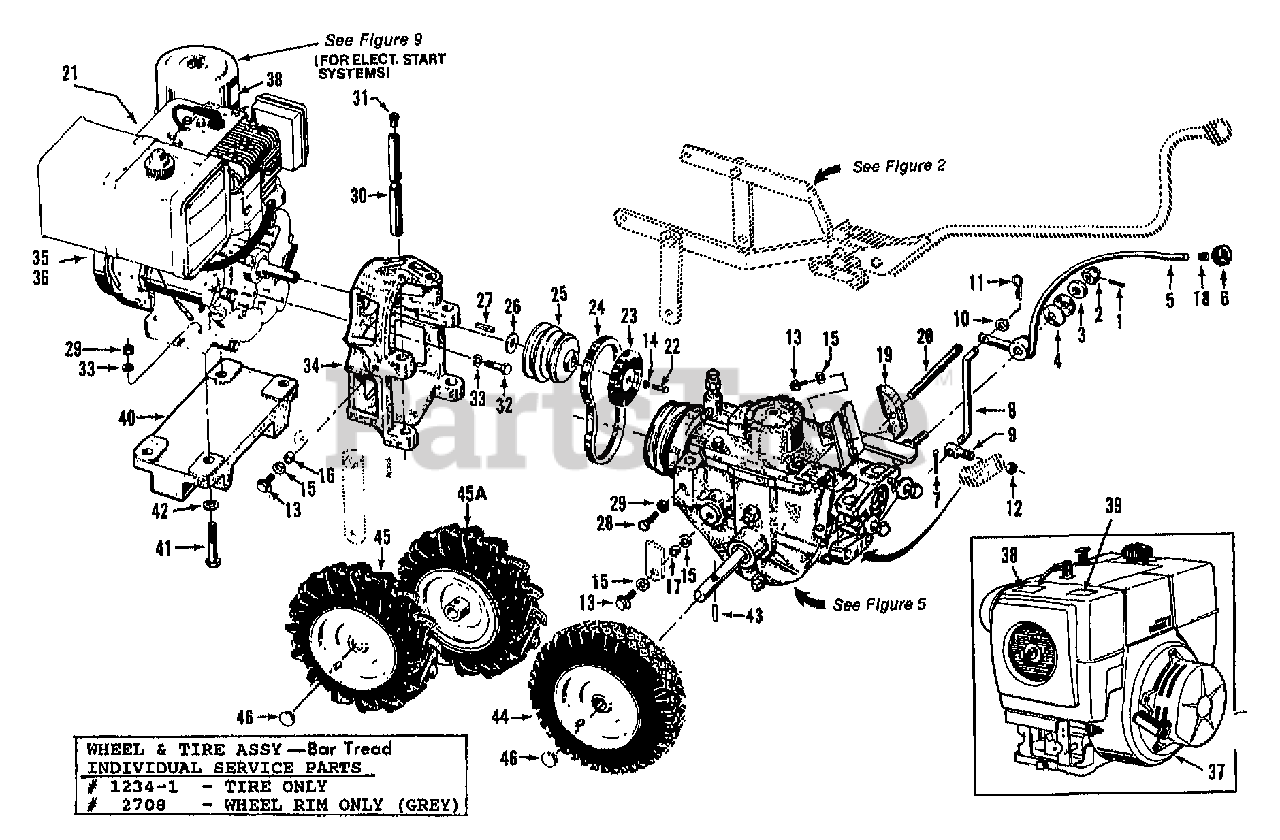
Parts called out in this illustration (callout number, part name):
1	PIN-SPRING .125 X 1
2	NUT-HEX 1/2-20
3	WASHER-# SHOULDER ZP (SHOULDER FACES DISC WASHERS)
4	WASHER-# 1.97X1X.118 (CONCAVE SURFACES FACE EACH OTHER)
5	LVR-W/KNOB - WHEEL SPEED (INCLUDES REF #6 AND REF. #18)
6	KNOB-WHEEL SPEED HORSE
7	PIN-COTTER .094X1.0
8	ROD-CONNECTING
10	WASHER-FLAT 5/16 SAE
11	PIN-CLIP .08
12	NUT-H/LK 5/16-18
13	SCR-HFLK 3/8-16X1.00 ZP
14	WASHER-LK .375 @ DEPL
15	WASHER-FLAT 3/8 SAE
16	BUSHING-.5X.375X.325
17	BUSHING-.5X.375X.3
18	RING-TOLERANCE .5325 ID
19	KIT-ADJ BLOCK 4 SP (INCL. 13,15,20)
20	BAR-ADJUST
21	DECAL-STARTING STABIL (FOR B & S ENGINE)
22	SCR-HH 3/8-24X1.5 G5
23	KIT-ADJ BLOCK/REV DISC (INCL. 19)
23	DISC-REV
24	BELT-V
25	PULLEY-ENG MACH
26	SHIM-1.0X.7656X.062
26	SHIM-1.0X.7656X.031
27	KEY-.188 SQ X 2.33
28	SCR-HH 5/16-18X1.0 G5 ZP
29	NUT-HEX 5/16-18 ZP
30	BAR-ENG MTG W/CAP PLUG
31	PLUG-CAP (RED)
32	BOLT-HH 5/16-24X1.125 G5 ZP
33	WASHER-LK .312 ZP
34	MOUNT-MOTOR HSE OPC PNT
35	7 HP BRIGGS & STRATTON ENGINE - RECOIL START
35	7 HP BRIGGS & STRATTON ENGINE - ELECTRIC START
36	8 HP BRIGGS & STRATTON ENGINE - RECOIL START
36	8 HP BRIGGS & STRATTON ENGINE - ELECTRIC START
37	8 HP KOHLER MAGNUM ENGINE - RECOIL START
37	8 HP KOHLER MAGNUM ENGINE - ELECTRIC START
38	DECAL-HOT SURFACE
39	DECAL-STABIL STARTING - FOR KOHLER ENGINE
40	WEIGHT-ENG ECONO PNT (B & S ENGINE ONLY)
41	SCR-HH 5/16-18X2.25 G5ZP
42	SPACER-.88X.385X.09 ZP
43	PIN-SPIROL .313 X 1.5
44	ASSM-STD TIRE
45	TIRE-LT BT GARDEN TRAC
45A	TIRE-RT BT GARDEN TRAC
46	CAP-HUB BLK PLASTIC
